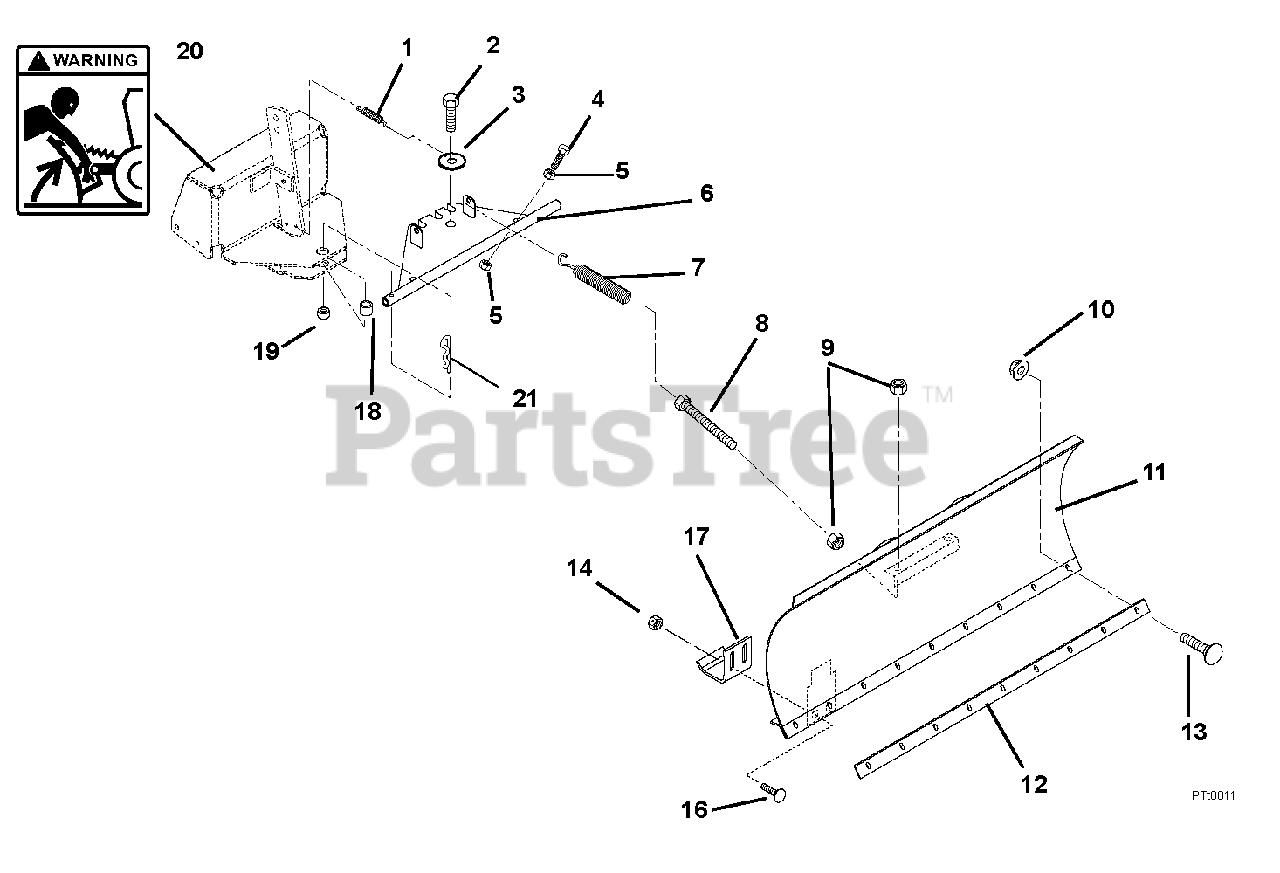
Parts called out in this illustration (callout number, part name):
1	Spring, Latch
2	Bolt, Hex .75-10 x 3.00 Grade 5
3	Washer, .38 Special
4	Bolt, Hex .50-13 x 2.00 Grade 5
5	Nut, Hex .50-13
6	Weldment, Pivot Plate
7	Spring, Blade Adjustment
8	Bolt, Hex .38-16 x 4.00 Full Thread
9	Nut, Hex .38-16
10	Nut, Locking-Top Flange .31-18
11	Weldment, 54" Blade
12	Plate, Wear
13	Bolt, Round Head Square Neck .31-18 x .75 Grade 5
14	Nut, Locking-Center .38-16
15	Bushing, Skid Pivot
16	Bolt, Round Head Square Neck, 3/8-16 x 1 Grade 5
17	Skid Shoes
18	Spacer .753 x 1.00 x 1.60
19	Nut, Locking-Jam-Nylon .75-10
20	Decal, Pinch Point
21	Internal Hair Pin, .15 x 2.937
